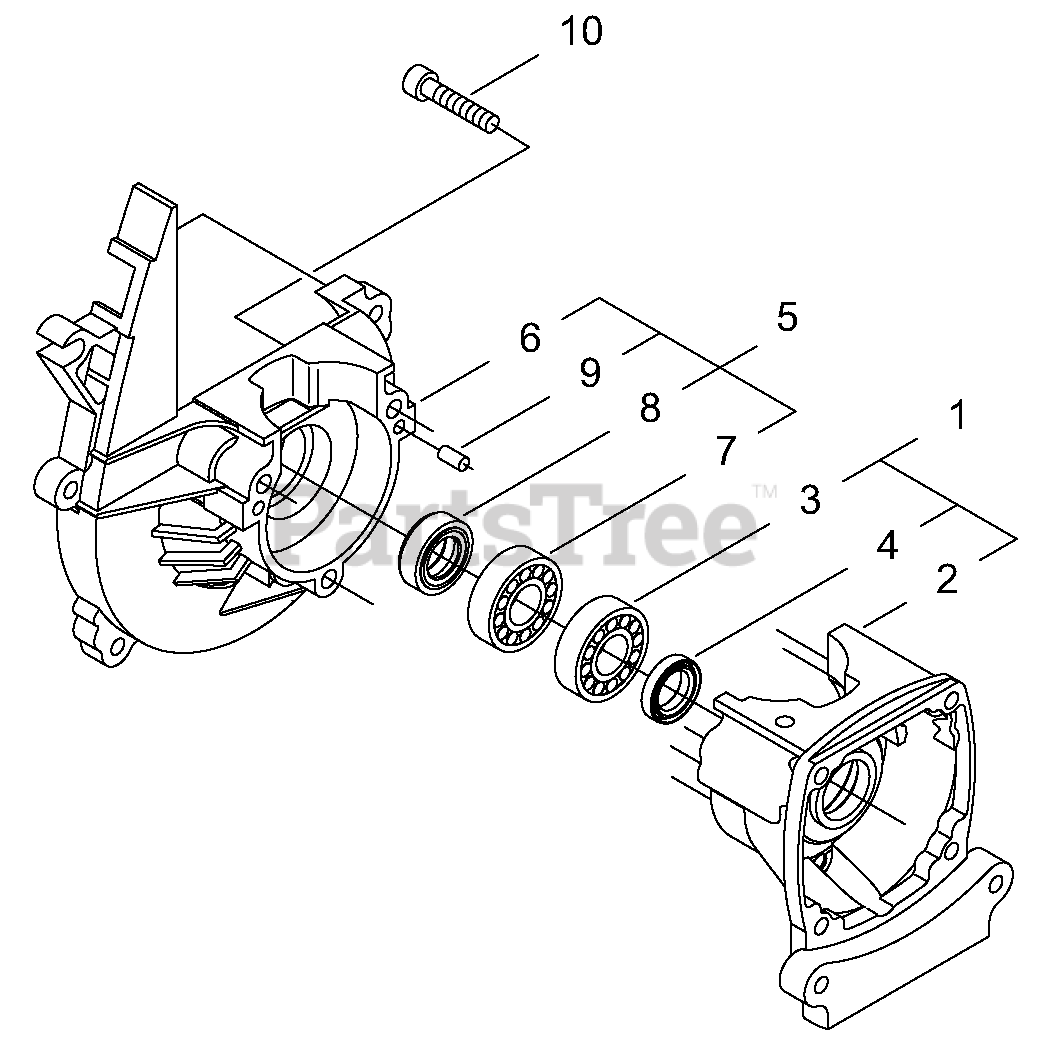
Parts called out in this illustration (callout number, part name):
1	CRANKCASE ASSY - REAR
2	CRANKCASE - REAR
3	BEARING, BALL - 6001
4	SEAL, OIL - 12
5	CRANKCASE ASSY - FRONT
6	CRANKCASE - FRONT
7	BEARING, BALL - 6001
8	SEAL, OIL - 12
9	PIN - LOCATING
10	SCREW - 5X25
11	SHORT BLOCK
12	CASE, FAN
13	BEARING, BALL - 6000ZZ
14	RING, RETAINING - 26
15	DRUM, CLUTCH
16	RING, RETAINING
17	CUSHION
18	SCREW - 5X16
19	SCREW - 5X45
20	ENGINE COVER ASSY
21	COVER, ENGINE
22	THUMBSCREW
23	INSULATOR
24	CLIP
25	WASHER - CONICAL
26	CLAMP, MAIN PIPE
27	CUSHION - FRONT
28	CUSHION - REAR
29	SCREW - 5X25
30	CAP
31	SCREW - 5X16
